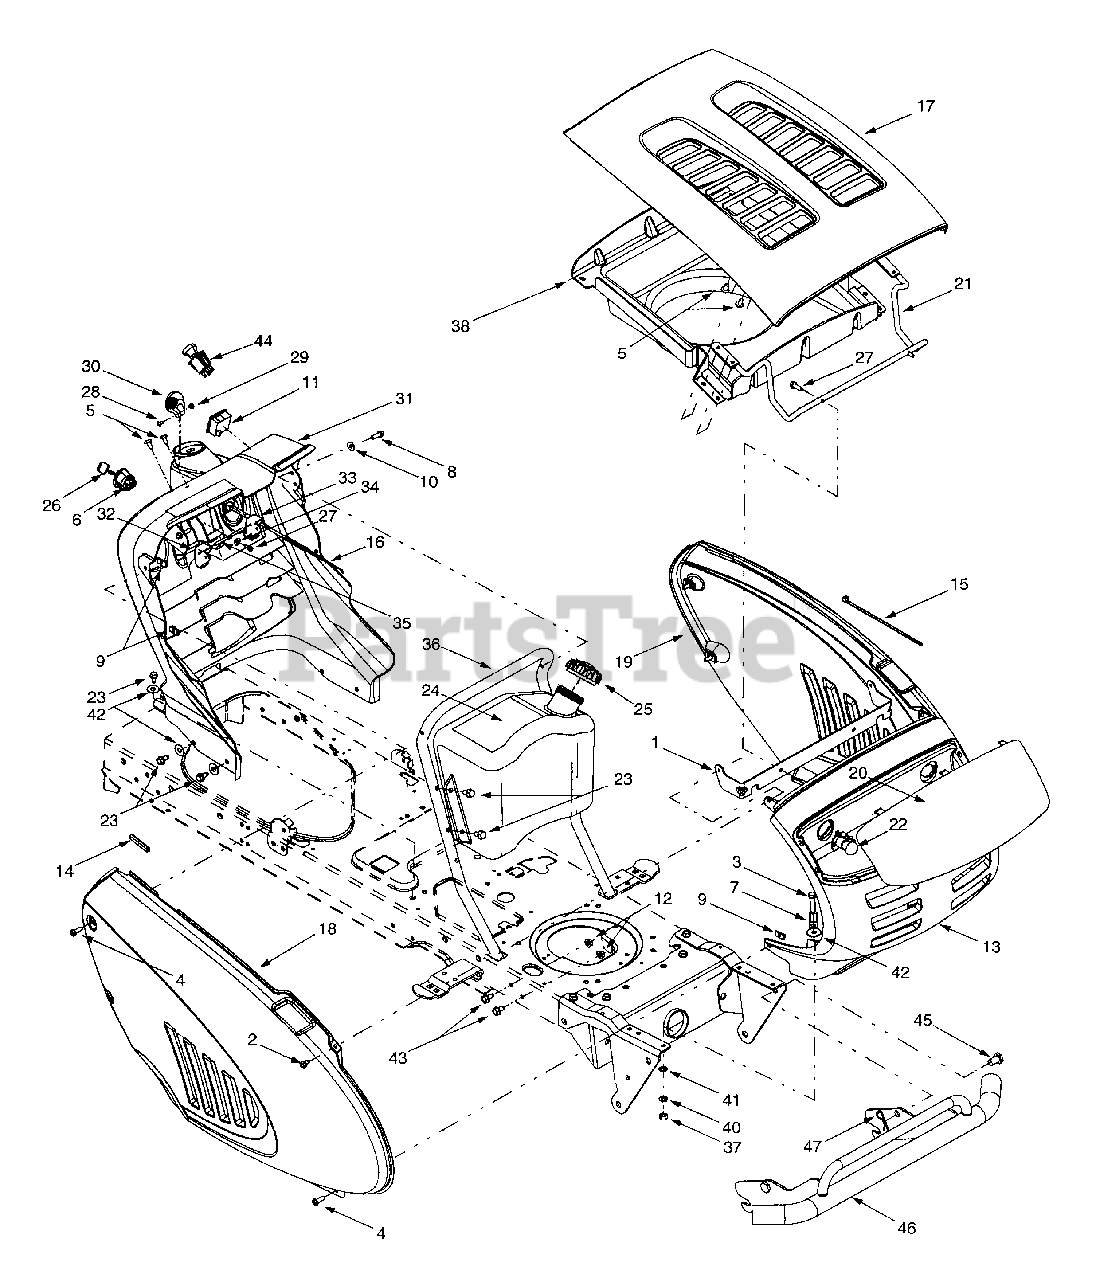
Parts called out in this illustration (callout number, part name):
2	Self-tapping Screw, 1/4-20 x .5
3	Hex Cap Screw, 5/16-18 x 1.25
4	Phillips Pan Screw, 1/4-20 x .75
5	Truss Phillips Screw, 1/4-20 x .625
6	Ignition Switch
7	Clamp, 9/16
8	Self-tapping Screw, 1/4-20 x .75
9	U-type Speed Nut, 1/4-20
10	Bell Washer, .265 x .75 x .062
11	Systems Indicator Monitor w/ Hour Meter
12	Hex Nut, 5/16-18
13	Grille (9-style)
14	Trim Strip, 4
15	Cable Tie, 3/16 x .05 x 7.4
16	Choke Knob/Cable
21	Hood Hinge Rod
22	Headlight Assembly
23	Self-tapping Screw, 5/16-18 x .625
24	Fuel Tank, Three Gallon
25	Fuel Cap
26	Ignition Key w/ plastic cover
27	Self-tapping Screw, 1/4-15 x .75
28	Truss Phillips Screw, #8-32 x .375
29	Hex Nut, #8-32
30	Throttle Control Knob
31	Dash Panel
32	Cruise Control Button
33	Parking Brake Button
34	Flat Washer, 9/32 x 1/2 x 1/16
35	Brake/Cruise Pivot Rod
38	Hood Plenum
40	Lock Washer, 5/16
41	Speed Nut, .3125
42	Flat Washer, .349 x 1.0 x .063
43	Screw, 5/16-18 x .875 (Grade 5)
44	Electric PTO Switch
45	Clevis Pin, .50 x .78
46	Bumper Assembly
47	Internal Cotter Pin
